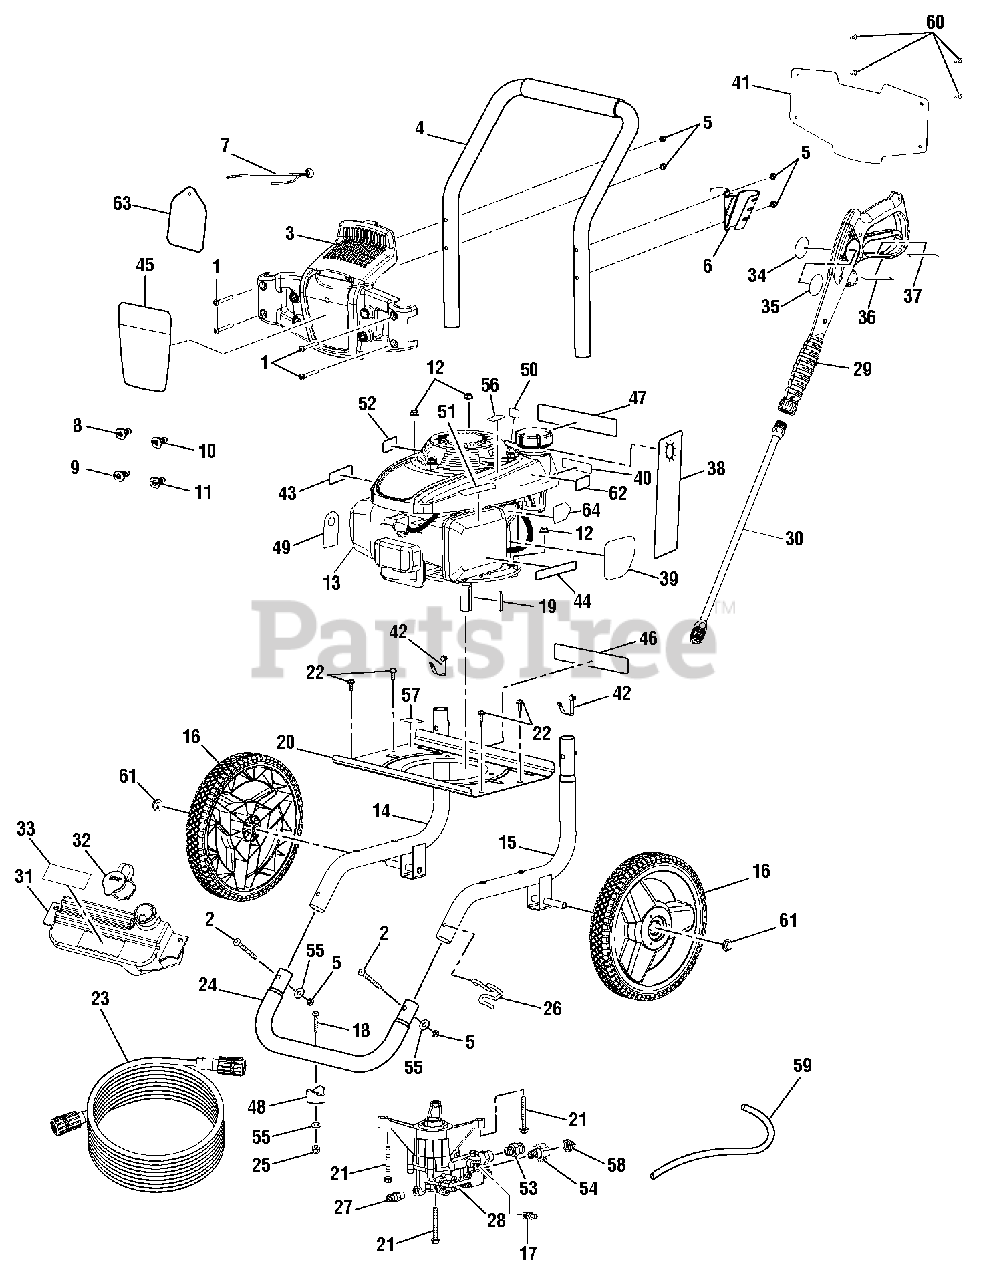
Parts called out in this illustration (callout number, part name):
1	Screw (M6 x 48 mm, T30 Torx Hd.)
2	Bolt (M6 x 55 mm)
3	Hose and Nozzle Holder Assembly
4	Handle w/Foam
5	Lock Nut (M6)
6	Wand Holder
7	Bungee Cord Assembly
8	40deg Nozzle
9	Soap Nozzle
10	25deg Nozzle
11	0deg Nozzle
12	Flange Nut (M8 x 1.25)
13	Engine (Honda GCV 160, 160cc OHC Vertical)
14	Main Frame Assembly
15	Main Frame Assembly
17	Detergent Suction Kit
18	Screw (1/4-20 x 1.85 in., T30 Torx Hd.)
19	Output Shaft Key (40 mm)
20	Engine Plate
21	Bolt (M8 x 60 mm, Flange Hd.)
22	Bolt (M6 x 16 mm)
23	Hose (25 ft., 3100 psi)
24	Front Frame
25	Lock Nut (1/4-20)
26	Wand Holder Loop
27	Thermal Release Valve
28	Pump
29	Trigger Handle Assembly
30	Extension Wand
31	Soap Tank
32	Soap Tank Cap
33	Soap Dilution Label
34	Label (Wand Logo)
35	Label (Wand Warning)
36	Fr/Sp Label (Wand Warning)
37	Label (Wand Rating)
38	Danger Hangtag
39	Engine Control Label
40	Combustion Label
41	Quick Start Panel
42	Lock Button w/Spring Clip
43	Hot Surface Label
44	EMC Label
45	Performance Label
46	Data Label
47	Danger Label
49	Dipstick Hangtag
50	No E85 Label
51	Inquiries Label
52	Lubricant Label
53	Outlet Tube
54	Inlet Tube
55	Washer (1/4 in.)
56	Release Water Label
57	Oil Fill Location Label
58	Filter Screen (Pump Inlet)
59	Chemical Siphon Tube
60	Screw (M3)
61	Push Cap Nut (1/2 in.)
62	Do Not Mix Label
63	Nozzle Hangtag
64	Engine On/Off Label
